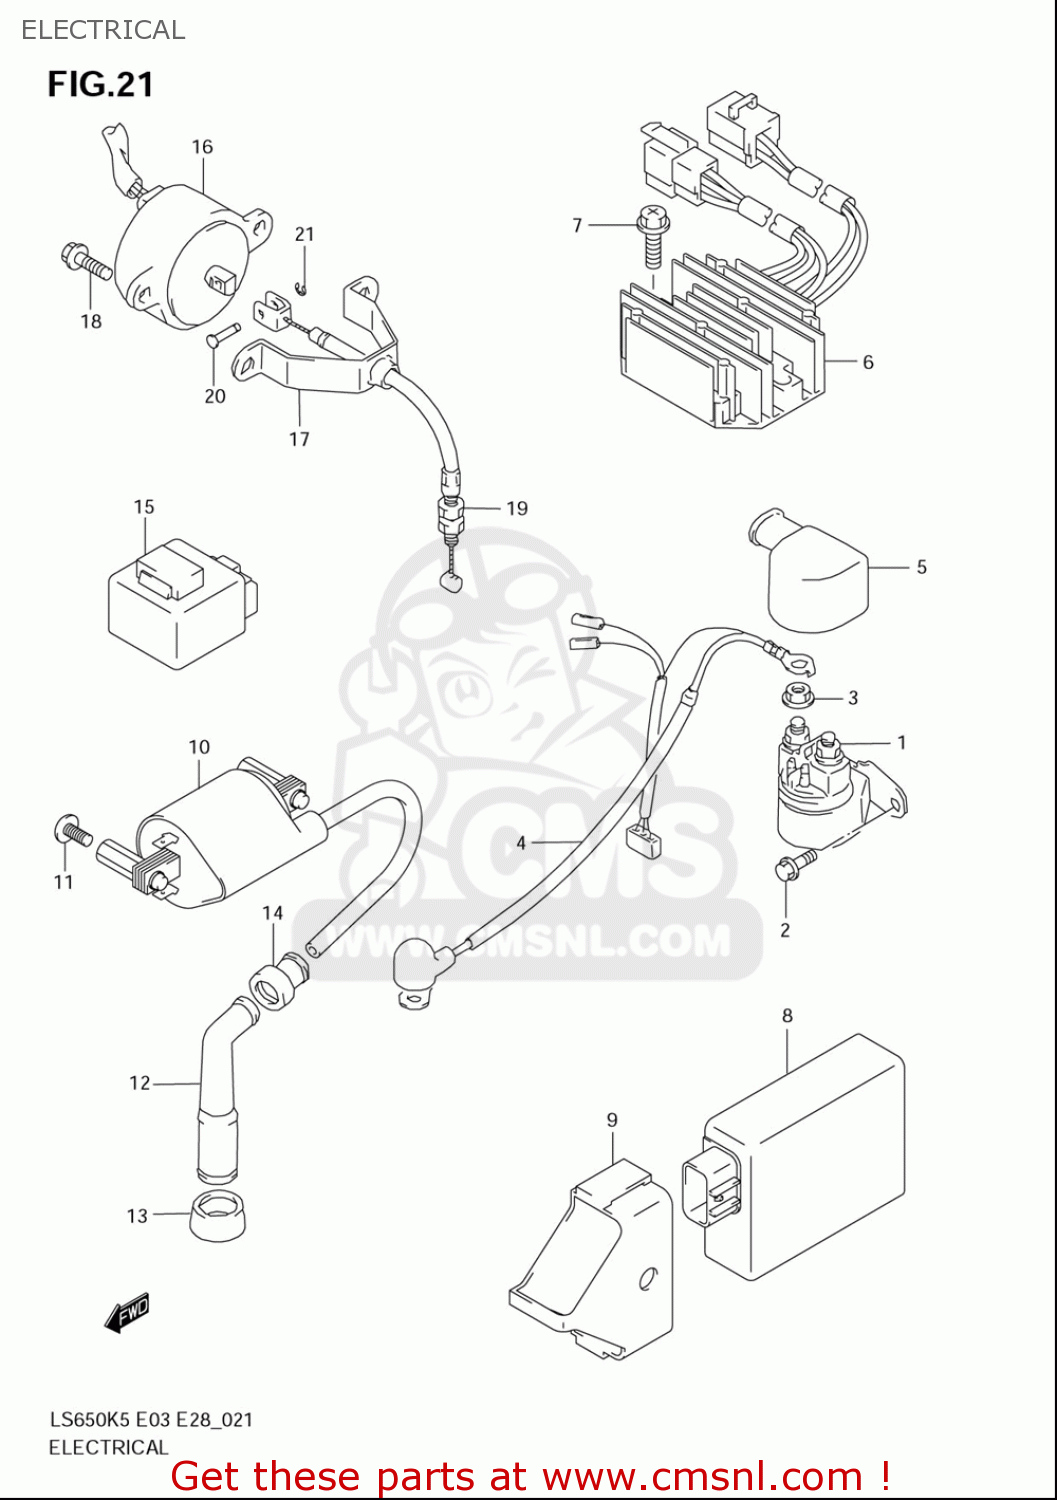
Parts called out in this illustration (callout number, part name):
1	RELAY ASSY,STARTING MOTOR
2	BOLT
3	NUT
4	WIRE,STARTER MOTOR
5	CAP,STARTER RELAY TERMINAL
6	RECTIFIER ASSY
7	BOLT
8	IGNITOR ASSY
9	CUSHION,IGNITOR
10	COIL ASSY,IGNITION
11	SCREW
12	CAP ASSY,SPARK PLUG
13	SEAL,SPARK PLUG
14	SEAL,HIGH TENSION CORD
15	CONTROL UNIT,DECOMP
16	SOLENOID ASSY,DECOMP
17	BRACKET,DECOMP SOLENOID
18	BOLT
19	CABLE ASSY,DECOMP
21	E RING
